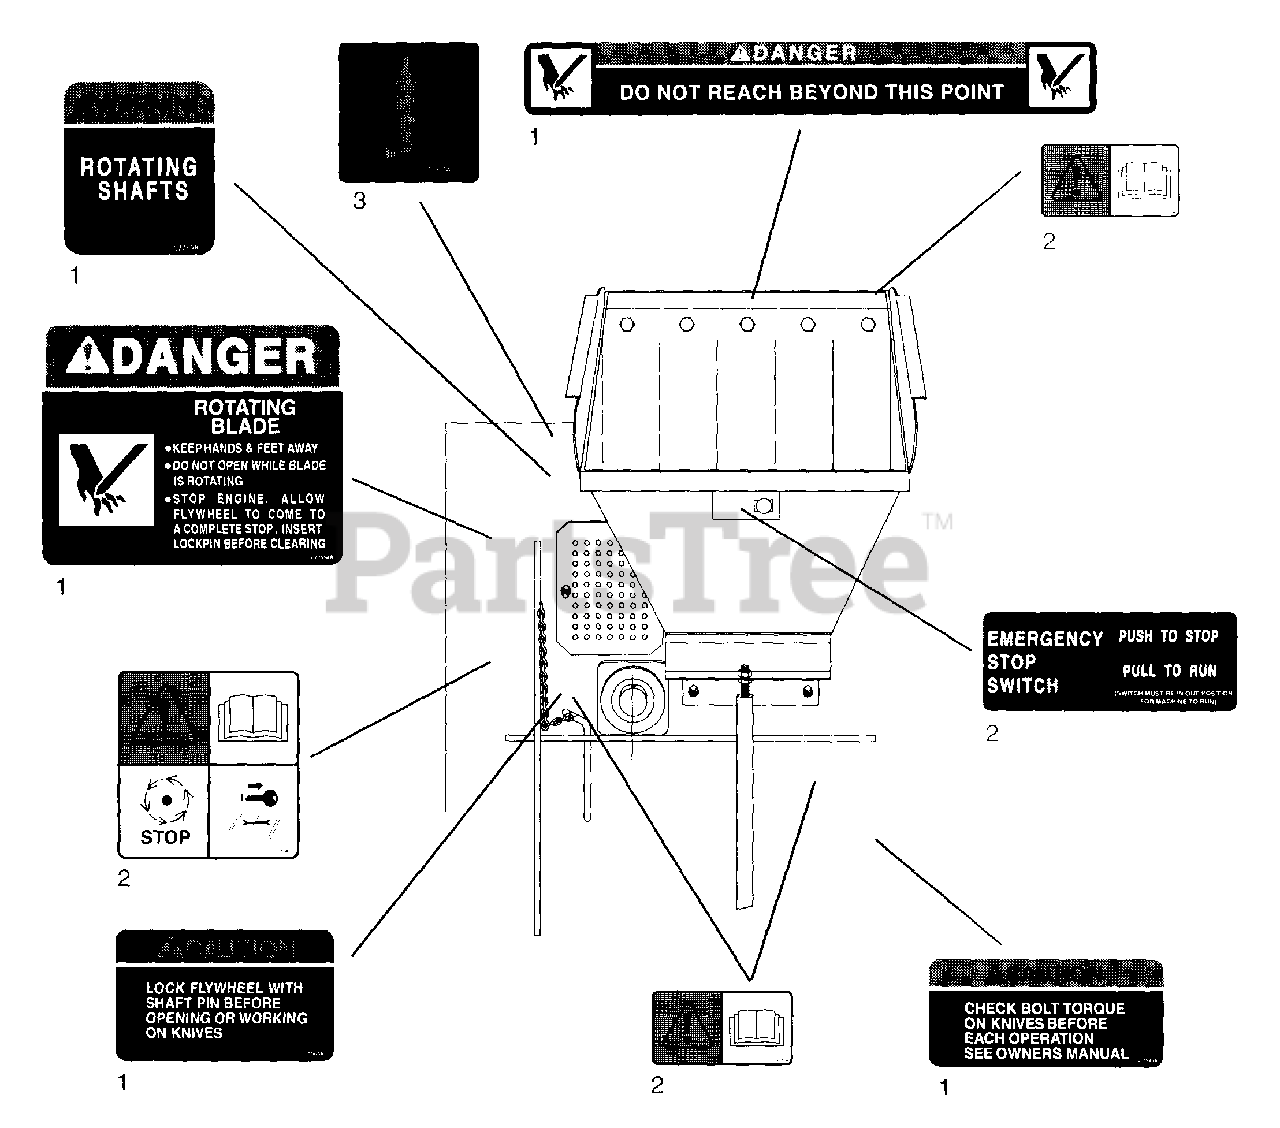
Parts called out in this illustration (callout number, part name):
1	Decal Set-Chipper
2	Decal Set-Chipper
3	Decal-Grease
4	Decal-PTO Warning
5	Decal-Pro Chip Logo
6	Decal-Gravely Logo
7	Decal-Push/Pull
